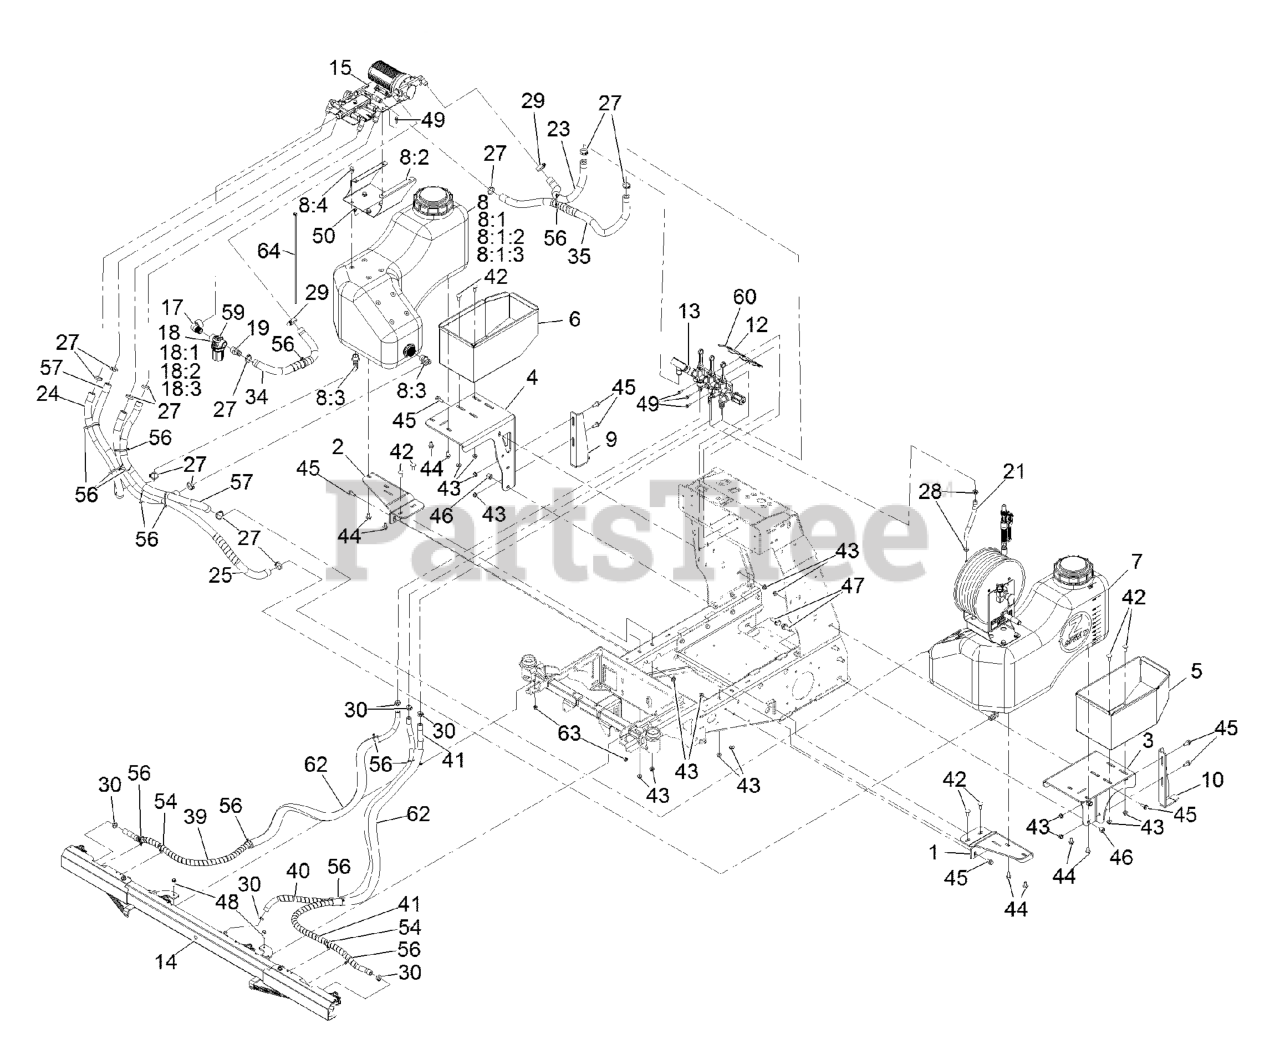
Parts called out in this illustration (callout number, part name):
1	Mount-Tank, LH Wing
2	Mount-Tank, RH Wing
3	Mount-Box, Lt Fert
4	Mount-Box, Rt Fert
5	BOX-FERT, LT
6	Box-Fert, Rt
7	ASM-Tank, Hose Reel
8	ASM-Tank, Rt
8:1	ASM-TANK, RT
8:1:2	CAP-TANK, SPRAY
8:1:3	FITTING-BULKHEAD
8:2	FITTING-ELBOW, 90
8:3	PLATFORM, LIQUID VALVE MO
8:4	Screw-HHF
9	Bracket-Anti-Tip, Rt
10	Bracket-Anti-Tip, Lt
12	BRACKET-MANIFOLD
13	ASM-Manifold
14	ASM, Boom
15	ASM, Liquid Valve
17	ELBOW-90DEG
18	STRAINER-INLINE
18:1	BOWL-STRAINER
18:2	GASKET-HEAD, LINE STRAINE
18:3	Screen-Strainer, 50 Mesh
19	HOSEBARB
21	Hose-Spray
23	Hose-Spray
24	Hose-Spray
25	Hose-Spray, Wrapped
27	Clamp-Oetiker, 167
28	CLAMP-OETIKER, 167
29	CLAMP-HOSE
30	CLAMP-OETIKER, 167
34	Hose-Spray, Wrapped
35	Hose-Spray, Wrapped
39	Hose-Spray, Wrapped
40	Hose-Spray, Wrapped
41	Hose-Spray, Wrapped
42	SCREW-CARR
43	Nut-Hex Flange
44	SCREW-HHF
45	SCREW-HHF
46	Nut,1/2-13,NYL INS,ST/ST,18-8
47	SCREW-HHF
48	SCREW-HHF
49	Screw-HHF
50	Nut-Hex Flange
54	CLIP-TIE
56	TIE-CABLE
57	Hose-Spray
59	DECAL-CAP, STRAINER
60	Decal-Valve, Boom
62	Guard-Mesh
63	Nut-Hex Flange
64	TIE-CABLE
